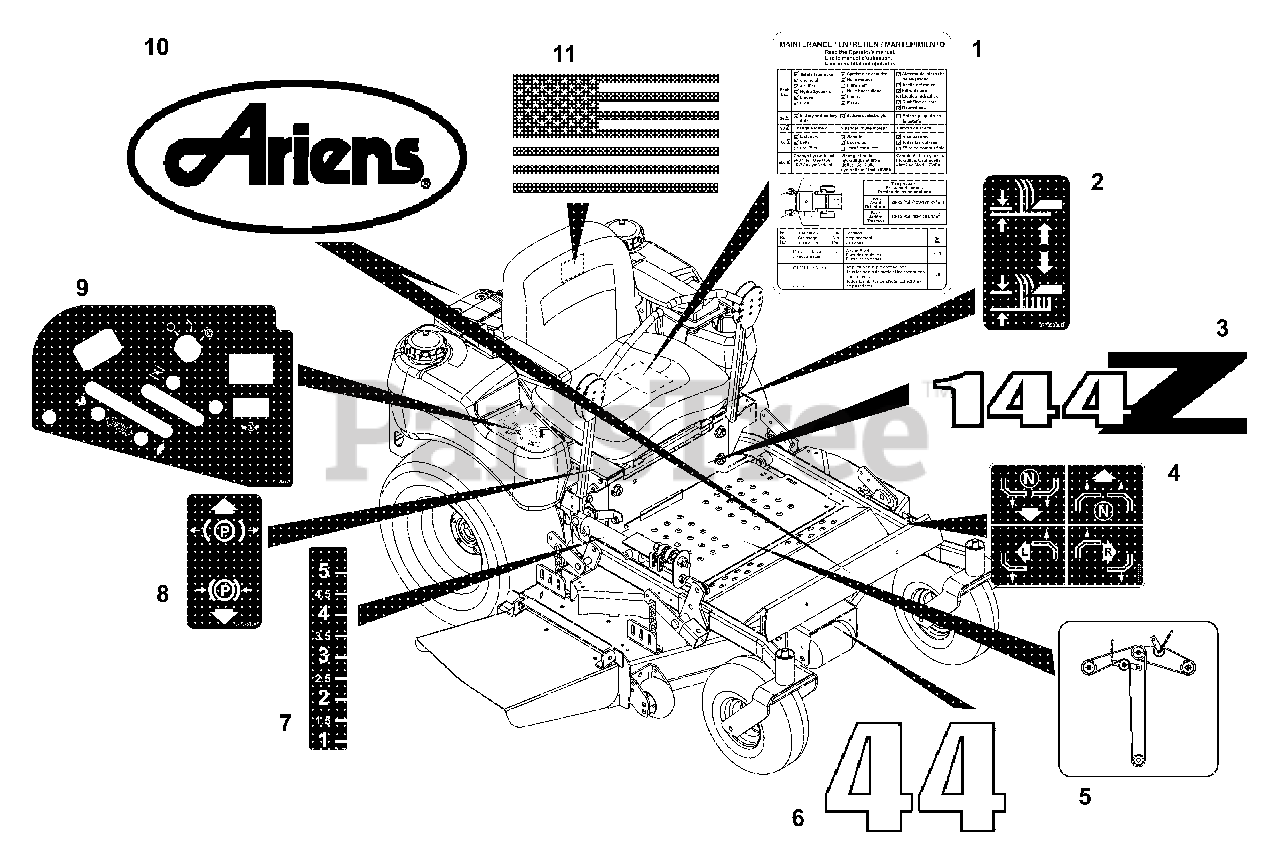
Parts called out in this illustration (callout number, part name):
1	DECAL, MAINTENANCE INSTRUCTION
2	DECAL- LIFT LEVER
3	DECAL, LOGO - GRAVELY 144Z
4	DECAL, INSTRUCTIONAL-STEERING
5	DECAL, GRAVELY BELT DIAGRAM
6	DECAL, 44"
7	DECAL, HEIGHT OF CUT
8	DECAL, PARKING BRAKE LEVER
9	DECAL CONTROL PANEL
10	DECAL, ARIENS
11	DECAL, AMERICAN FLAG
